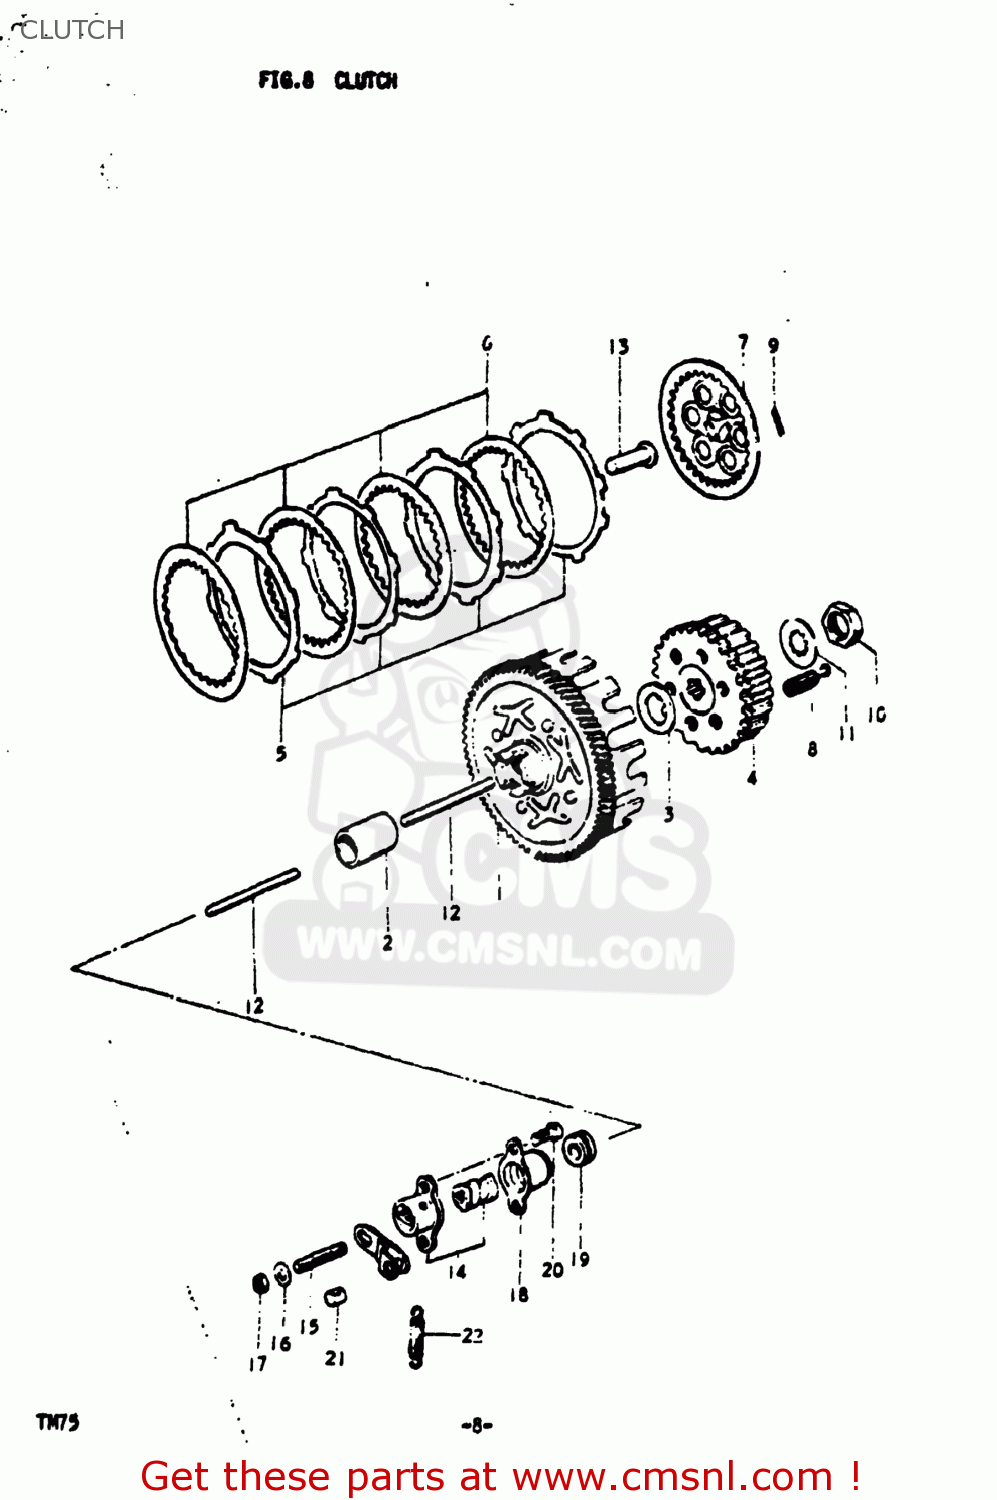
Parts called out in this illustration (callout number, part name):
1	GEAR ASSEMBLY,PRIMARY DRIVE
2	SPACER (17X21X52)
3	WASHER
4	HUB,CLUTCH SLEEVE
5	PLATE,CLUTCH DRIVE (MCA)
6	PLATE,CLUTCH DRIVEN (NAS)
7	PLATE,CLUTCH PRESSURE
8	SPRING
9	PIN(2.5X19.8)
10	NUT
11	WASHER,LOCK
12	ROD,CLUTCH PUSH
13	PIECE,CLUTCH PUSH
14	SCREW ASSEMBLY,CLUTCH RELEASE
15	SCREW
16	WASHER(6.5X16X1.2)
17	NUT
18	COVER,CLUTCH RELEASE SCREW
19	SEAL,DUST(5.3X13X5)
20	SCREW
21	PIECE,RELEASE ARM END
22	SPRING
